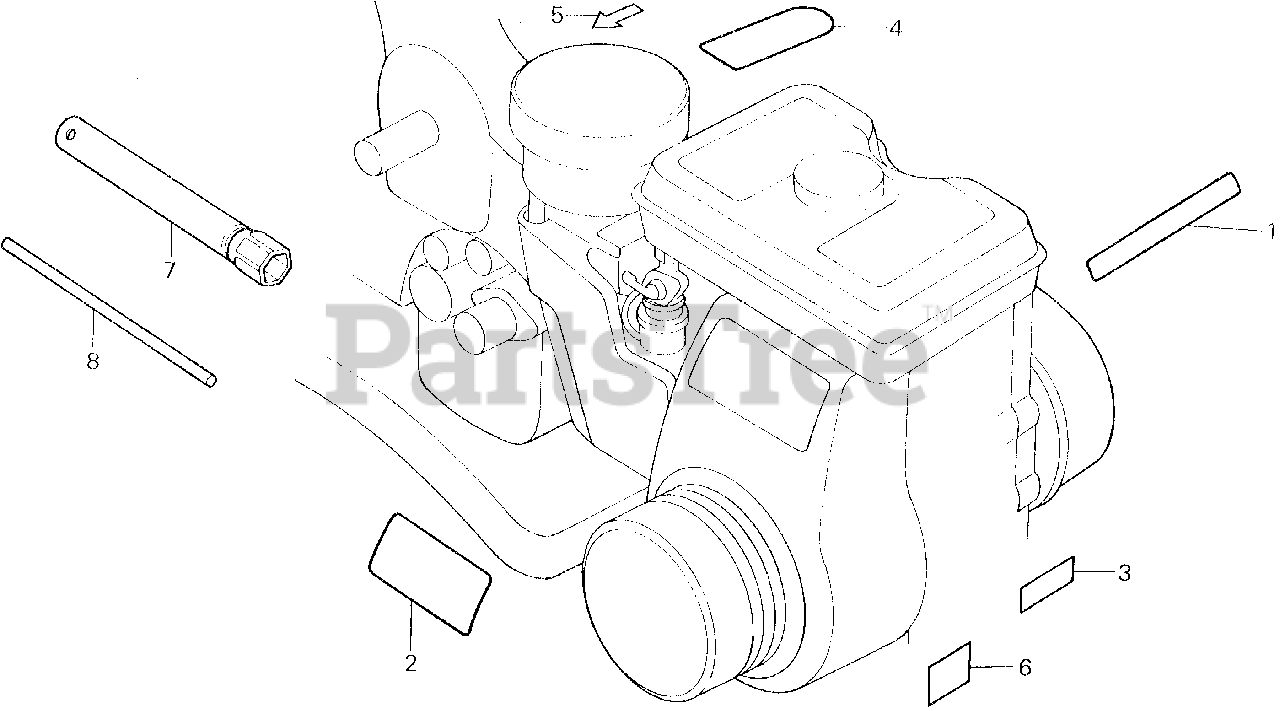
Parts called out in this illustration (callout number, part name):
1	MARK, TOP COVER
2	MARK, FAN COVER (NOT AVAILABLE)
4	MARK A, CAUTION (ENGLISH/FRENCH)
5	MARK, CHOKE
7	WRENCH, SPARK PLUG
8	HANDLE, BOX WRENCH
